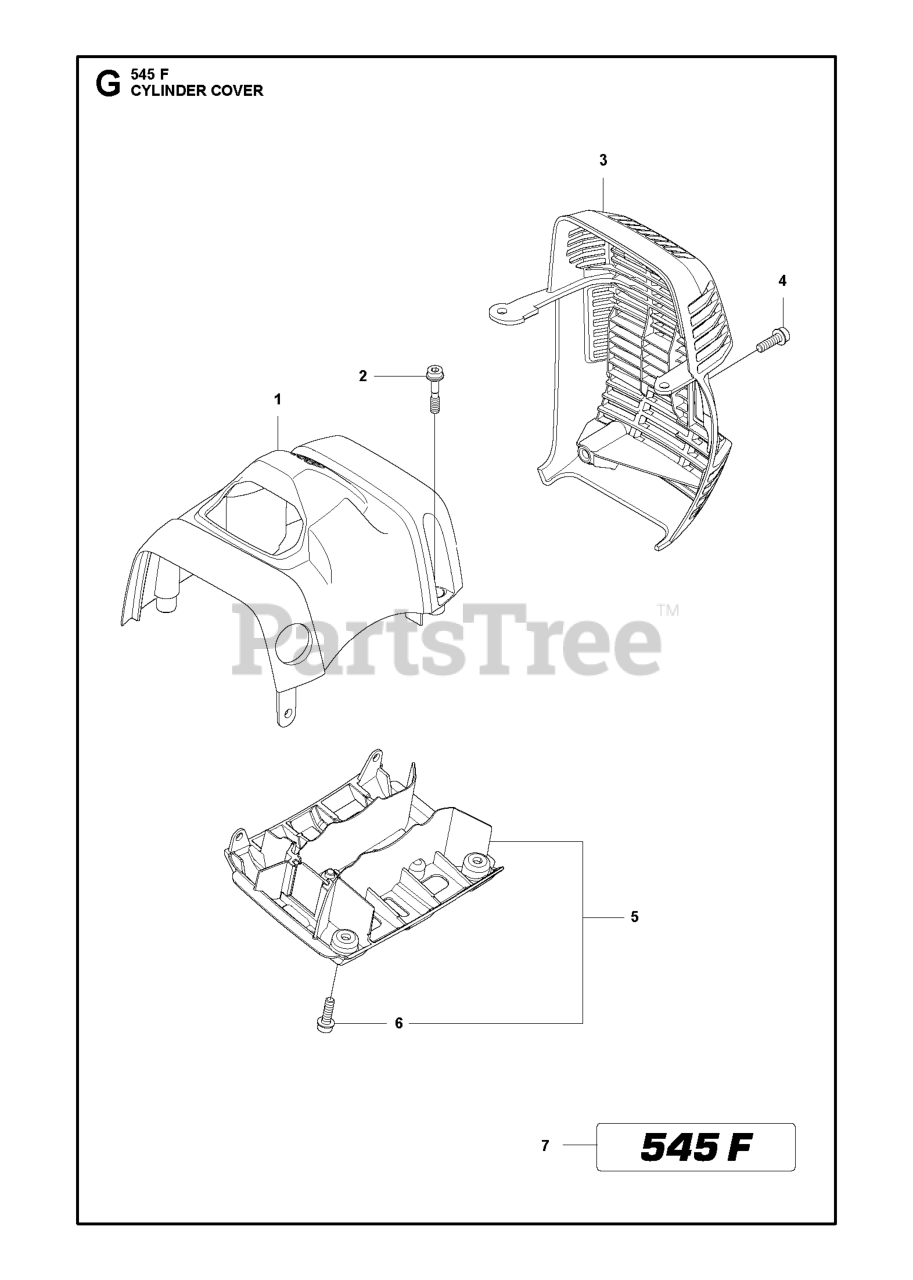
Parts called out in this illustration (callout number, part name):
1	CYLINDER COVER
2	SCREW IHSCFMO
3	HEAT PROTECTOR
4	SCREW IHSCFM
6	SCREW IHSCFM
